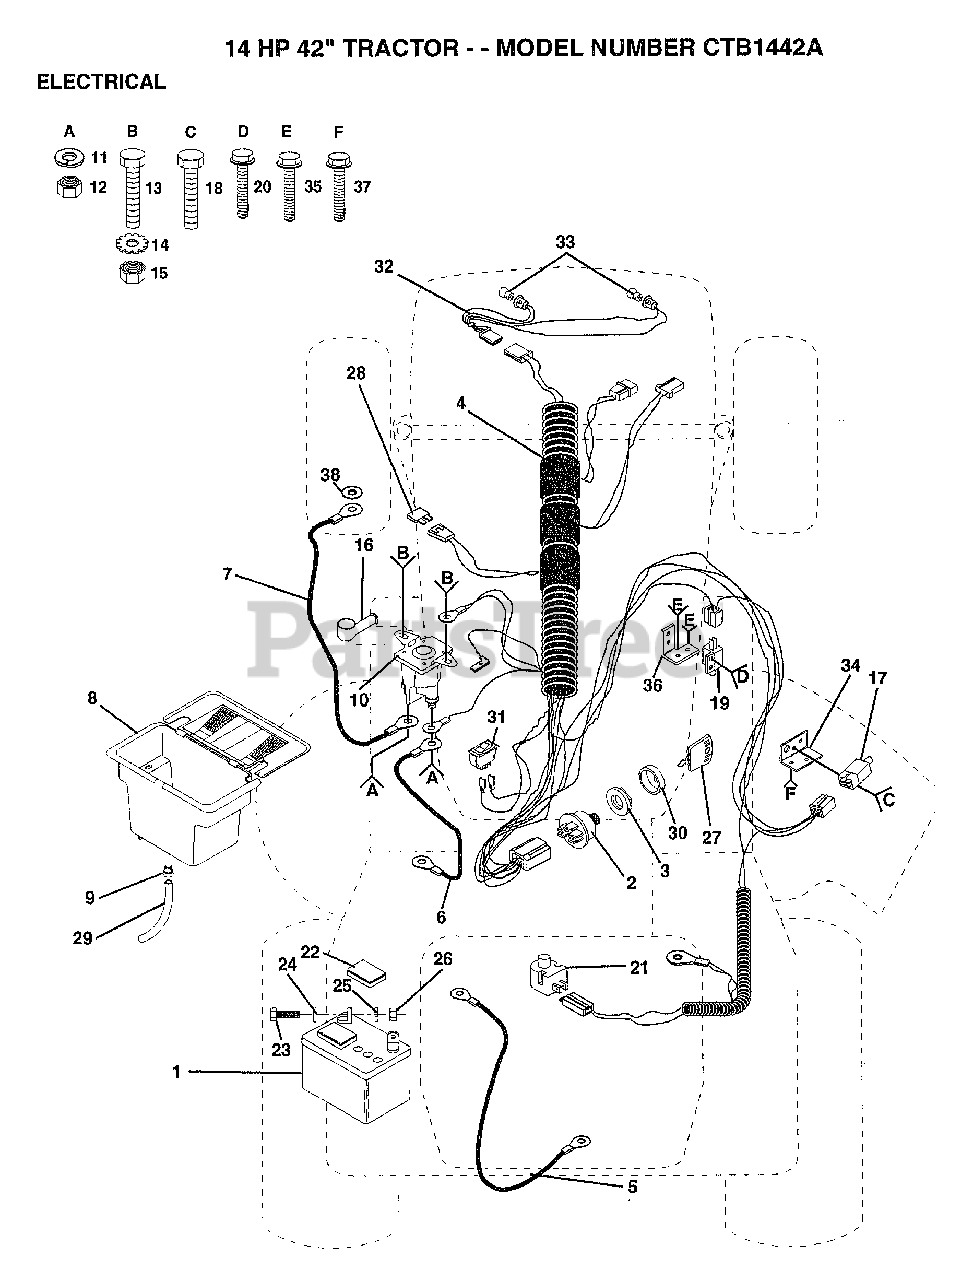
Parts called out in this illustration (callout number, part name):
3	NUT IGNITION
4	IGN HARNESS
5	CABLE T
7	"CABLE T, BATTERY"
9	HOSE CLAMP T
12	NUT
13	BOLT
15	NUT
17	SWITCH INTERLOCKT
18	SCREW
19	SWITCH-INTER. GT
20	SCREW
21	SWITCH SEAT
22	"CAP,BATTERY "
23	BOLT LT
24	WASHER
25	LOCKWASHER
27	KEY
28	FUSE HYT
29	TUBE T
31	SWITCH LT
32	"HARNESS,LIGHT SOC"
33	HEADLAMP BULB
34	BRACKET LT
35	SCREW
36	SWITCH BRACKET
37	SCREW
38	LOCKWASHER
